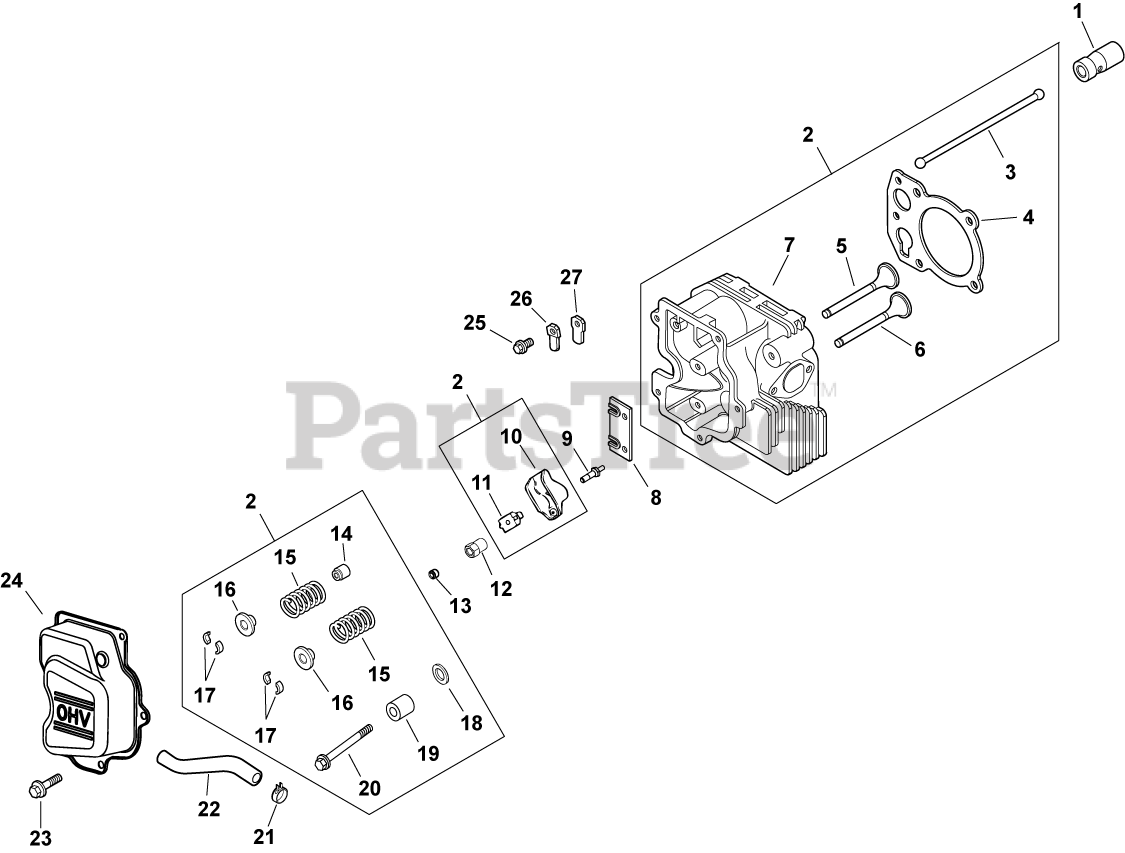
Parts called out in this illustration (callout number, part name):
1	LIFTER, HYDRAULIC VALVE-USE 25 351 10-S
2	KIT, CYLINDER HEAD HARDWARE
3	ROD, PUSH - DISCONTINUED
4	GASKET, CYLINDER HEAD
5	VALVE, INTAKE
6	VALVE, EXHAUST
7	HEAD ASSEMBLY, CYLINDER - DISCONTINUED
8	PLATE, GUIDE
9	STUD, ROCKER
10	ARM, ROCKER
11	PIVOT, ROCKER ARM
12	NUT, HEX (AVT)-USE 25 100 38-S
13	SCREW, SET (AVT)-USE 25 086 168-S
14	SEAL, VALVE STEM - (#2503214S)
15	SPRING, VALVE
16	RETAINER, VALVE SPRING - USE 25 173 28-S
17	KIT, RETAINER
18	WASHER, FLAT 13/32"
19	SPACER - DISCONTINUED
20	SCREW, CYLINDER HEAD (M10 X 80)
21	CLAMP, HOSE (KM)-USE 25 237 31-S
22	HOSE, BREATHER
23	SCREW,FLG THD FRM M6X1.0X16-(#25086397S)
24	COVER, ROCKER
25	SCREW, FLG THD FRM M5X.8X10
26	RETAINER, REED
27	REED, BREATHER
